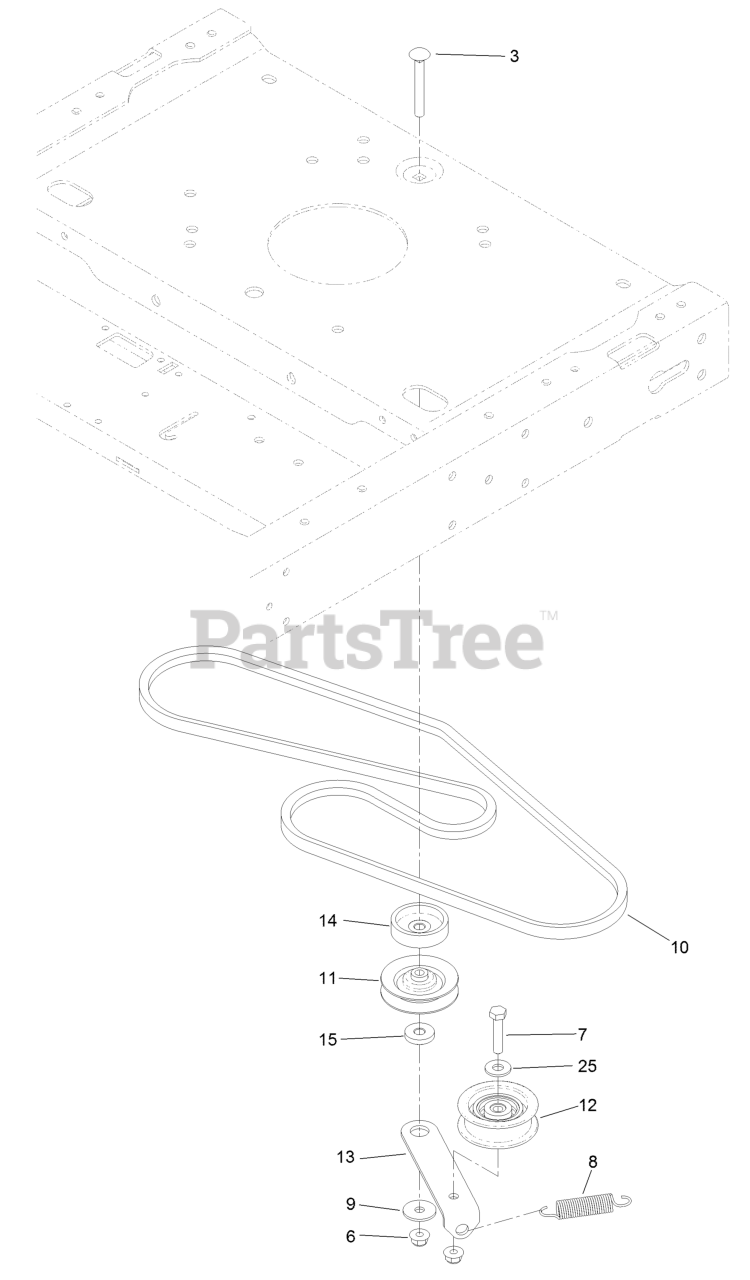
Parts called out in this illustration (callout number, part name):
3	SCREW-CARR
6	NUT-HF, NI
7	SCREW-HH
8	SPRING-RETURN, PEDAL
9	WASHER-PIVOT
10	V-BELT
11	PULLEY-IDLER
12	PULLEY-IDLER
13	ARM-IDLER
15	SPACER-ARM, IDLER
25	WASHER-FLAT
